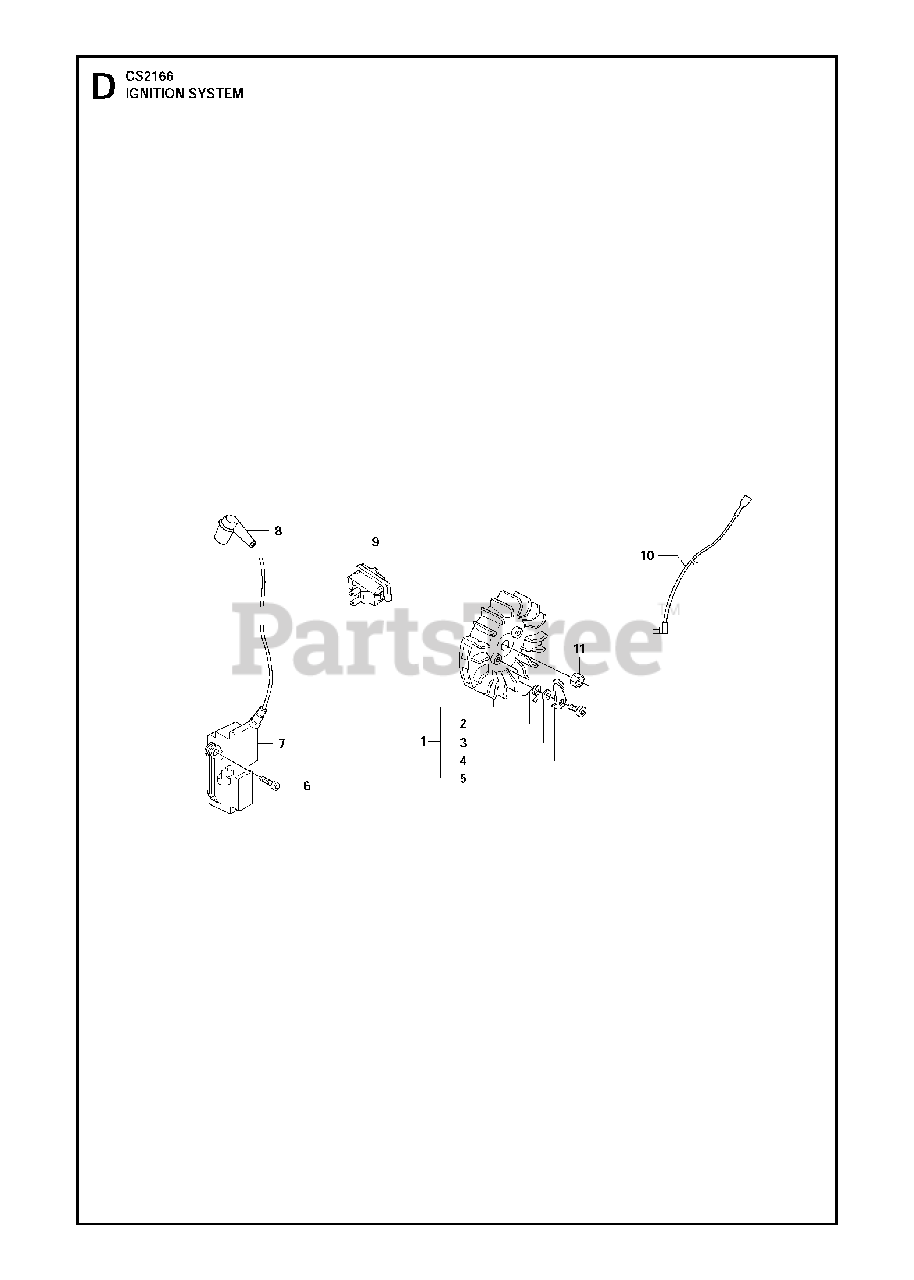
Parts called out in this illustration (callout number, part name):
2	SPRING
3	WASHER
4	PAWL
5	SCREW M5X14
7	IGNITION MODULE
8	SPARK PLUG CONN. KIT
9	START/STOP SWITCH
11	NUT W/ WASHER
